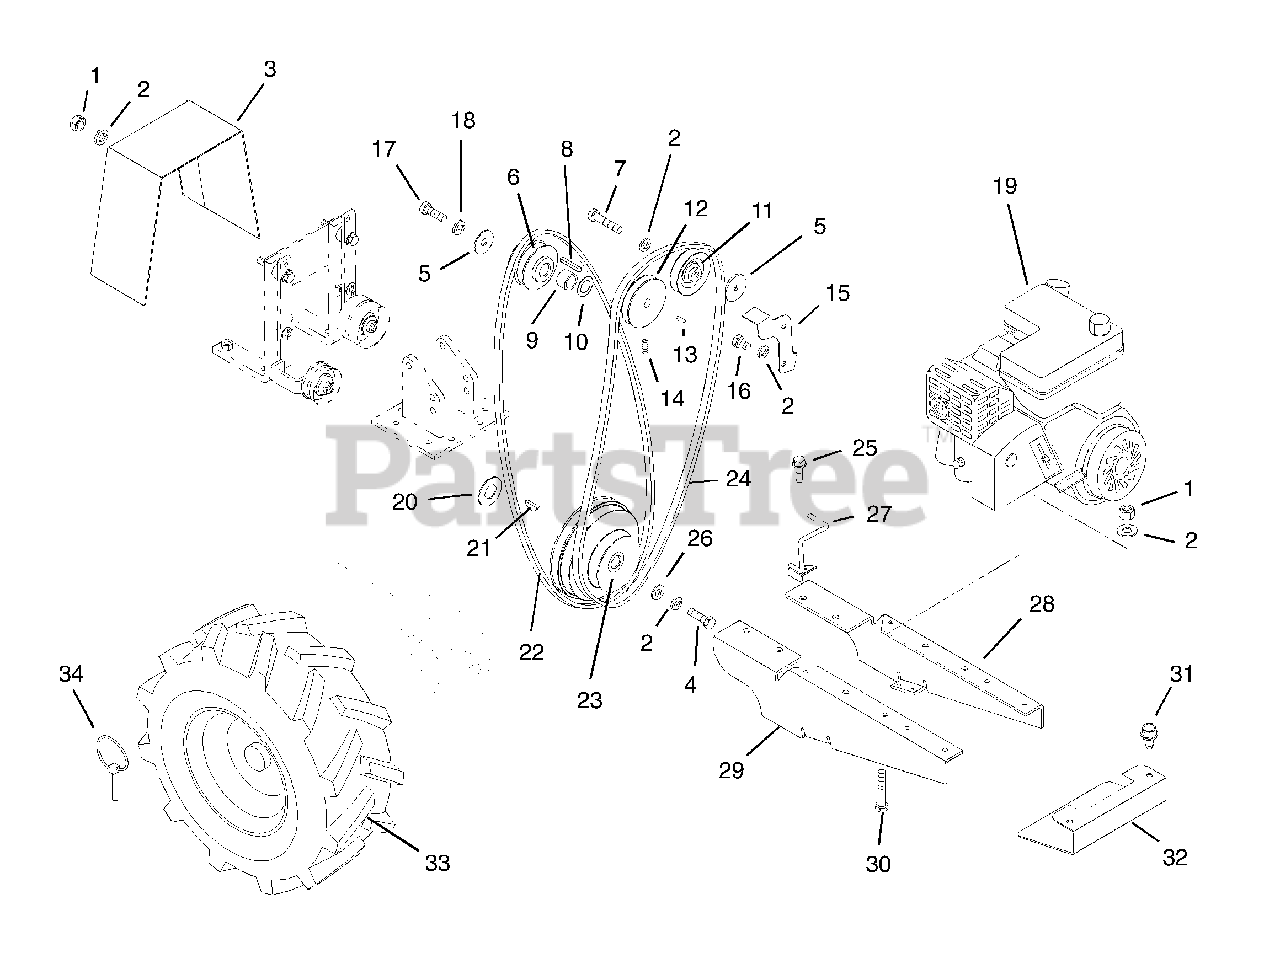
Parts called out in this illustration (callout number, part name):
1	@NUT-HEX .31-18 YWZC
2	@WSHR-LK .31X.078 REG YWZC
3	BELT GUARD W/DECALS (OPC)
4	@BLT-HEX .31-18X1.00 GR5 YWZC
5	@WSHR-FL-STL.38X.875X.083 YWZC
6	SHEAVE, FORWARD
7	BLT-HEX .31-24X1.50 GR5 YWZC
8	KEY-SQ .188X1.5X.187 SAE 8630
9	SPACER .765X.875X.870
10	WSHR-HDND-THRST .758X1.23X.031
11	IDLER-V 2.625X.312
12	SHEAVE REVERSE OHH50
13	KEY-WDRF .125X.625X.250 SAE5
14	SCR-SET .25-20X.25 SKHCUPDL
15	BELT FINGER
16	SCR-CAP .31-24X.50HH GR5 YWZC
17	BLT-HEX .31-24X1.00 GR5 YWZC
18	@WSHR-LK .31X.078 REG YWZC
19	ENGINE, B&S INTEK 20HP V TWIN
20	WSHR-FL-STL .699X1.375X.059
21	KEY-WDRF .188X.75X.313 SAE 9
22	V-BELT, 4L-WRAPPED
23	SHEAVE - TRANSMISSION
24	V-BELT, 3L-WRAPPED
25	SCR-TAP .25-20X.75 HWH TR YWZ
26	WSHR-FL-STL .328X.87X.179 YWZC
27	FINGER, BELT SER 18"
28	L H ENGINE MTG BRKT
29	R H ENGINE MTG BRKT
30	@BLT-HEX .31-18X1.75 GR5 YWZC
31	@SCR-TAP .31-18X.50 HWH TR YWZ
32	COVER, ENGINE BRKT
33	T/WHL ASSY RH
34	PIN-LOK .31X2.00
